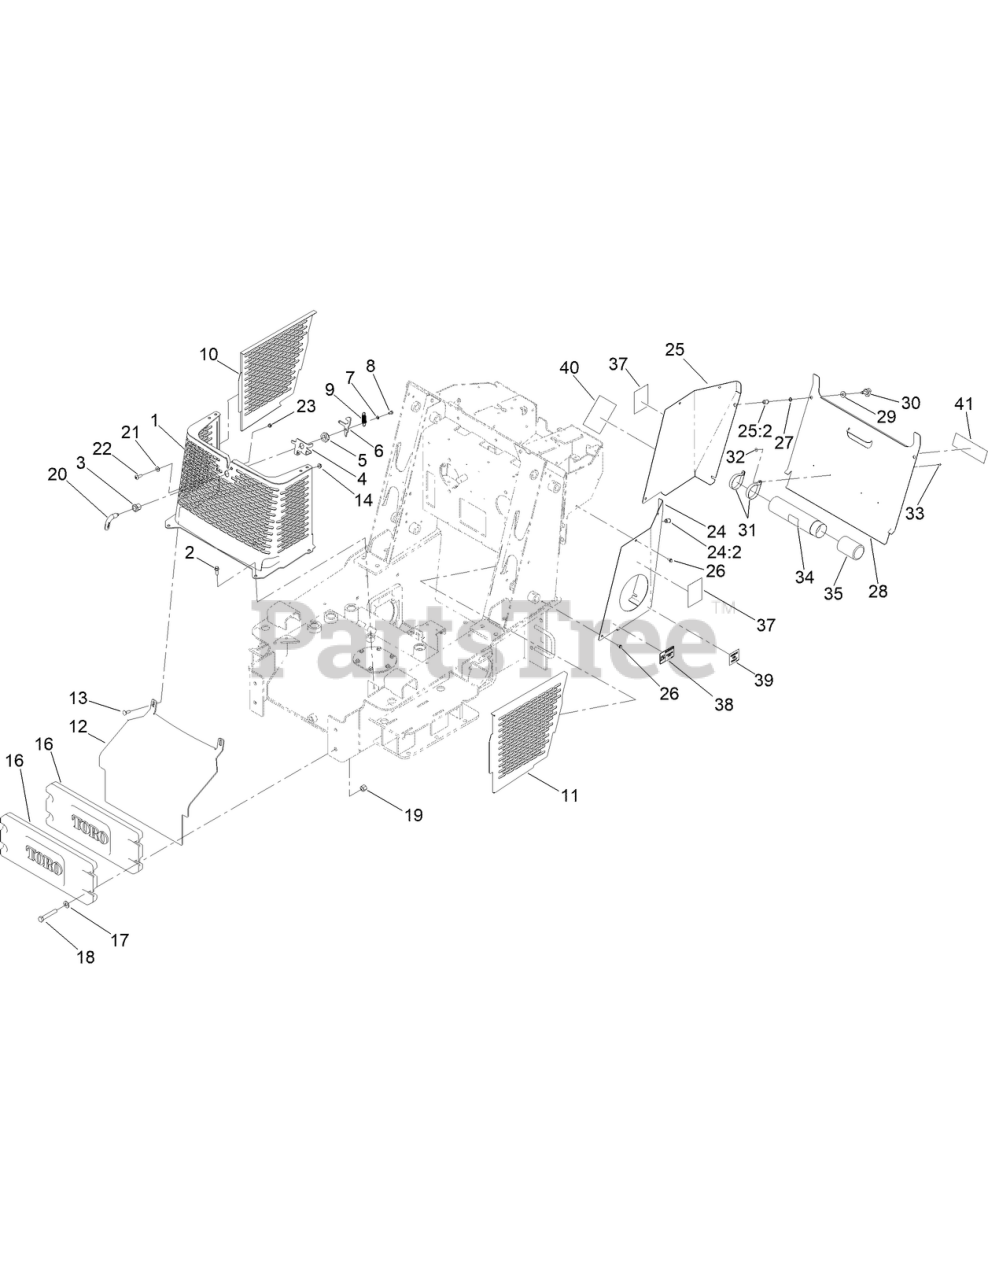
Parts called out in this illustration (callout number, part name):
2	SCREW-TAPTITE
3	HOUSING-LATCH
4	BRACKET-LATCH
6	CAM-LATCH
7	WASHER-LOCK
8	SCREW-HH
9	SPRING
10	PANEL-SIDE, RH
11	PANEL-SIDE, LH
12	PLATE-FRONT
13	SCREW-CARR
14	NUT-HF
16	COUNTERWEIGHT-FRONT
17	WASHER-FLAT
18	SCREW-HH
19	NUT-LOCK, NI
20	HANDLE-LATCH
21	WASHER-FLAT
22	SCREW-PTH
23	NUT-LOCK, NI
24	LH REAR COVER SUPPORT ASM
24:2	NUT-CLINCH
25	RH REAR COVER SUPPORT ASM
25:2	NUT-CLINCH
26	SCREW-HWH
27	RING-RETAINING
28	COVER-ACCESS, REAR
29	WASHER-RUBBER
31	CLAMP-R
32	WASHER-BACK
33	RIVET-POP
34	TUBE-MANUAL
35	CAP-HOUSING
37	DECAL- RHVSG3X4
38	DECAL-CPER0011
39	DECAL-CPER0003
40	DECAL-CPER0001
41	DECAL-CPER0014
